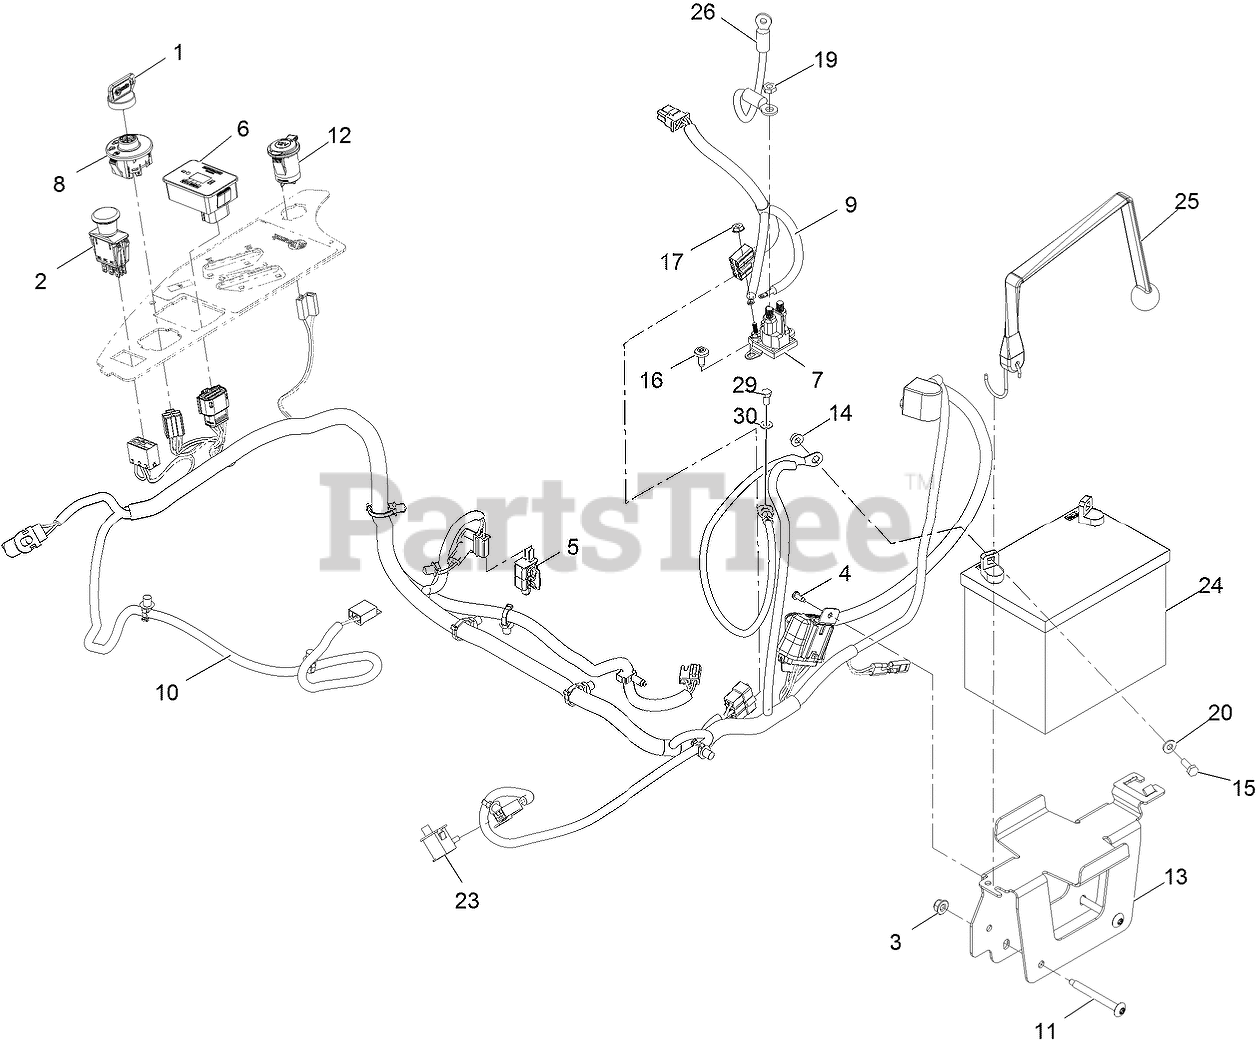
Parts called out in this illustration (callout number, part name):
1	KEYS-IGNITION (SPARE PAIR
1	KEY-IGNITION
2	SWITCH-PTO
3	NUT-HF, NI
4	SCREW-FORMING, THREAD
6	MODULE ASM
7	SOLENOID
8	SWITCH-IGNITION
9	ADAPTER-HARNESS, WIRE
10	HARNESS-WIRE
11	SCREW-TORX
12	PORT-POWER, 12V
13	TRAY-BATTERY
15	SCREW-HH
16	SCREW-TORX
17	NUT-KEPS
19	NUT-JAM
20	WASHER-FLAT
23	SWITCH-BAIL
24	Battery
25	STRAP-BUNGEE
26	CABLE-BATTERY, POSITIVE
29	SCREW-HH
30	WASHER-PLAIN
